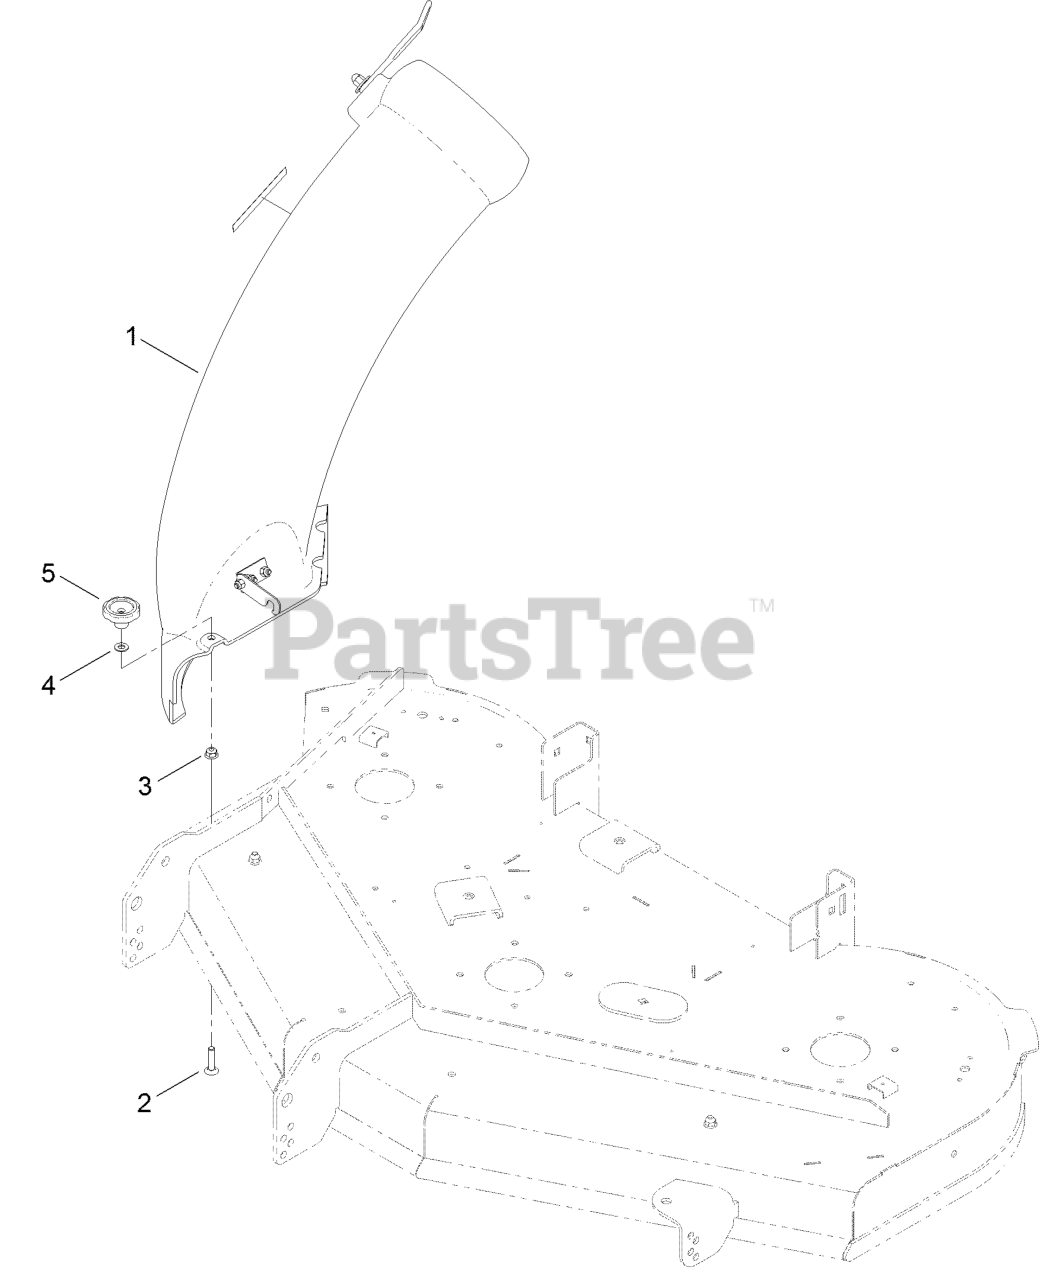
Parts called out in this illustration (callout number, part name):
1	50 INCH CHUTE ASM
2	SCREW-CARR
3	NUT-HF, NI
4	WASHER-PLAIN
